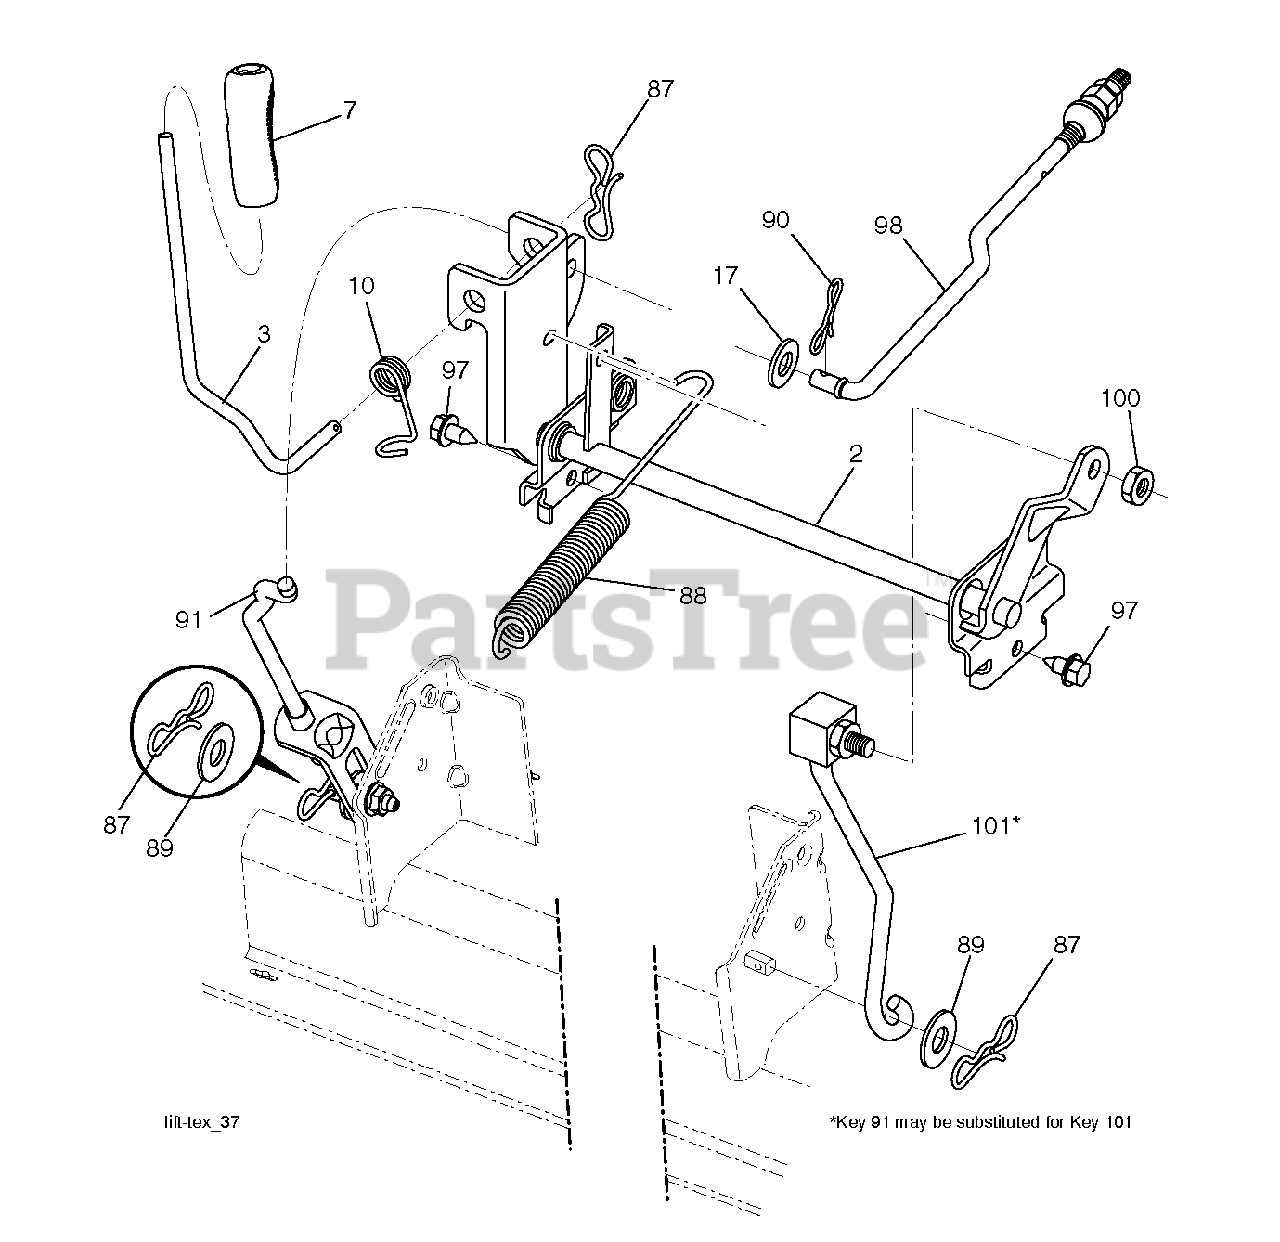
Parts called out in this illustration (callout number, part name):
2	SHAFT.ASM.CROSS.LIFT
3	LEVER.LIFT.HANDLE.GT
10	SPRING.TORSION.LIFT.HANDLE
17	WASHER
87	PIN.COTTER.7/16.BOW TI
88	SPRING.LIFT.ASSIST
89	WASHER.CLEAR.ZINC
90	PIN.COTTER.5/16.BOW TI
91	LINK.ASM.LIFT.REAR
97	SCREW, 3/8-16X3/4
98	LINK.ASM.SUSP.FRONT.MW
100	LOCKNUT
101	LINK.ASM.LIFT.FIXE.38/42/46"
